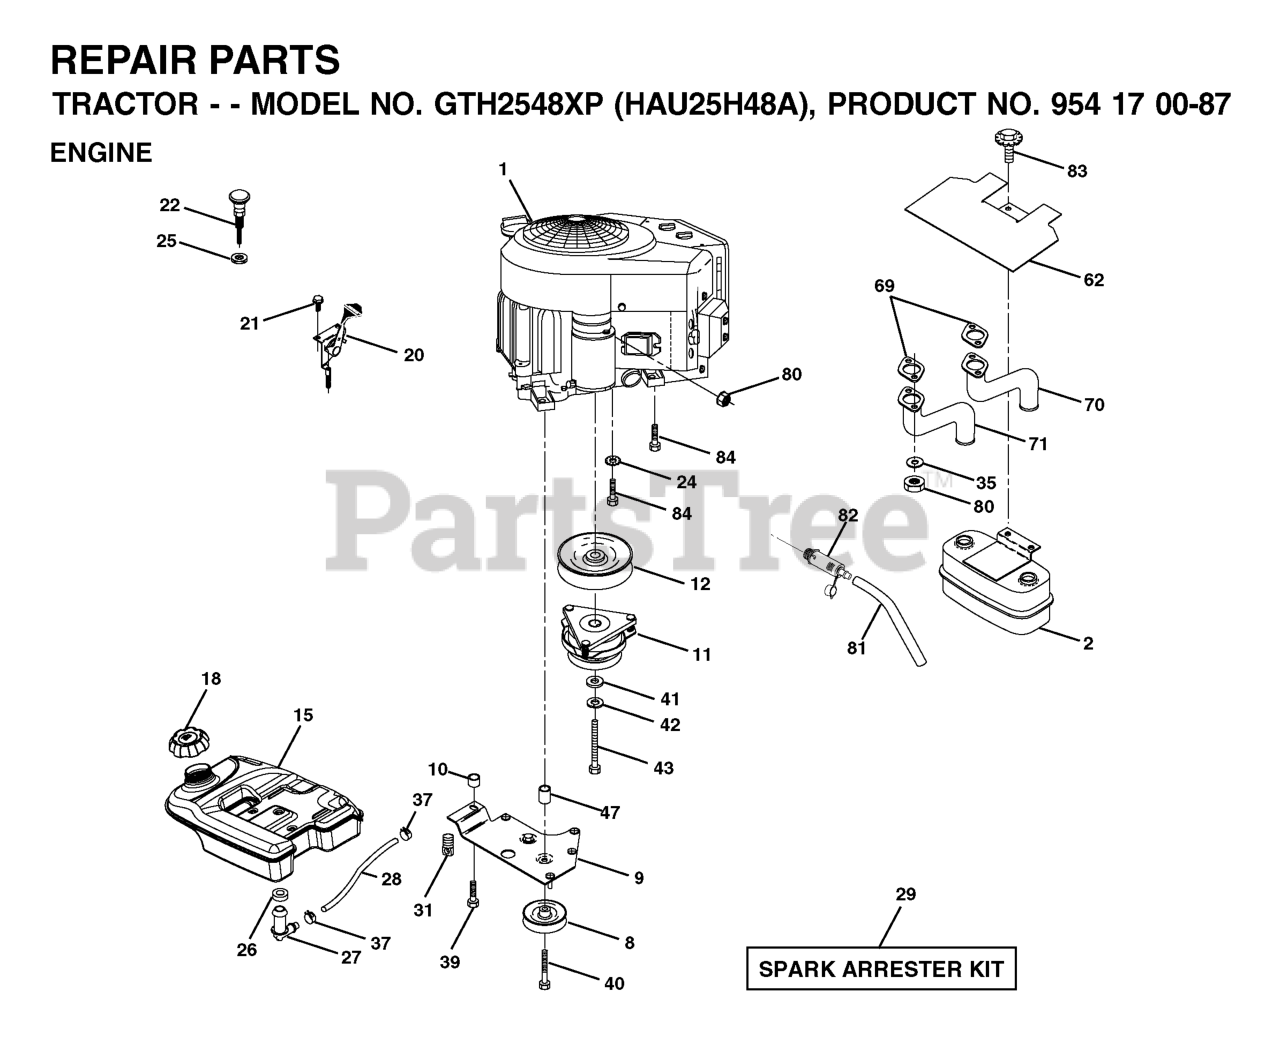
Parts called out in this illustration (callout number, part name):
3	APPLIQUE.SUBASM.GT.HUSQ.II
5	DASHBOARD.TEX.GT2.UPPER.S.PTO
14	HOOD.ASM.HUSQVARNA.GT.TEX.ORAN
15	LED LIGHT.LH
18	GRILLE SUBASM.GT.II.LOW.HDLGHT
25	LENS.RH
34	PLATE.ENGINE.WELDED.CHASSIS
36	SCREW 5/16"
37	FENDER.TLT.FS.W/CPH/FW/RSF.668
52	LOCKNUT
58	DRAWBAR UPPER 2PC SMALL FENDER
68	SCR 5/16-18 X 1/2 SELFTAP ZN
125	CLIP.FUEL.LINE
130	SCREW.#10 X 0.750.BOS
137	BUMPER DASH
146	BOLT.RDHD.SHT.SQNK.3/8-16X5/8
150	AIR.DUCT.GTV.BLACK
151	BRACKET.PIVOT.HOOD.GT.HUSQ.II
152	SHIELD.BROWNING.PNT.GT.V2
161	WINDOW.FUEL.LT.HUSQ.TEX.498
162	SCREW.HI-LO.CONSOLE
165	SUPPORT.TANK.REAR.W/TEX
175	PLATE.PNT.CROSSMEMBER.HUSQ/PRE
176	SCREW.#10-24X5/8.RN.QU
177	BUSHING STEERING
180	CHASS.WLDMNT.TL.12GA/2P.48/54
182	DASH.LOWER.COMMON.12V.ADAPTOR
183	BOLT.5/16-18X1-1/4 FULL THD
189	SCREW
191	INSERT INFLECT.RH
194	NUT LOCK HEX FLANGE 5/16-18
195	PLUG.HOLE.DASH.LOWER.12V.BLK
202	VENT.SIDE.RH.GT.HUSQ.II.
203	VENT.SIDE.LH.GT.HUSQ.II.498
204	VENT.TOP.HUSQ.GT2
205	SIDE.TRIM.RH.GT.HUSQ.II
206	SIDE.TRIM.LH.GT.HUSQ.II.GRAY
207	BEZEL GT2 LED RH W/ LOWER.ATT
208	BEZEL GT2 LED LH W/ LOWER ATT
213	BOLT
214	CLIP.RETAINER.TINNER.
217	ROD.PIVOT.HOOD
218	X-PIECE.HOOD.STOP.NON/
228	STUD.FASTNER.W/ANTI-ROTATE
233	BOLT.SHOULDER
235	SPACER FENDER
236	NUT.CENTERLOCK.5/16-
282	CLIP.RETAINER.CONSOLE.LT.HUSQ
284	CONCOLE.CNTRL.PDL.HUSQ.LT.498
285	CONSOLE INSERT RH
286	CONSOLE.INSRT.LH.HUSQ.LT.BLACK
287	SCREW 1/4X20
296	LED LIGHT.LH
297	INSERT REFECT LH
299	LED LIGHT.RH
306	NUT LOCK FLG 3/8-16 UNC
335	COVER.LOWER.DASH.RH.BLACK
336	COVER-LH.LOWER.DASH.GT2.BLACK
350	CLIP.X-MAS.TREE
375	BUMPER CLIP-ON. DASH 1"
378	BUSHING FLANGE; PLASTIC
